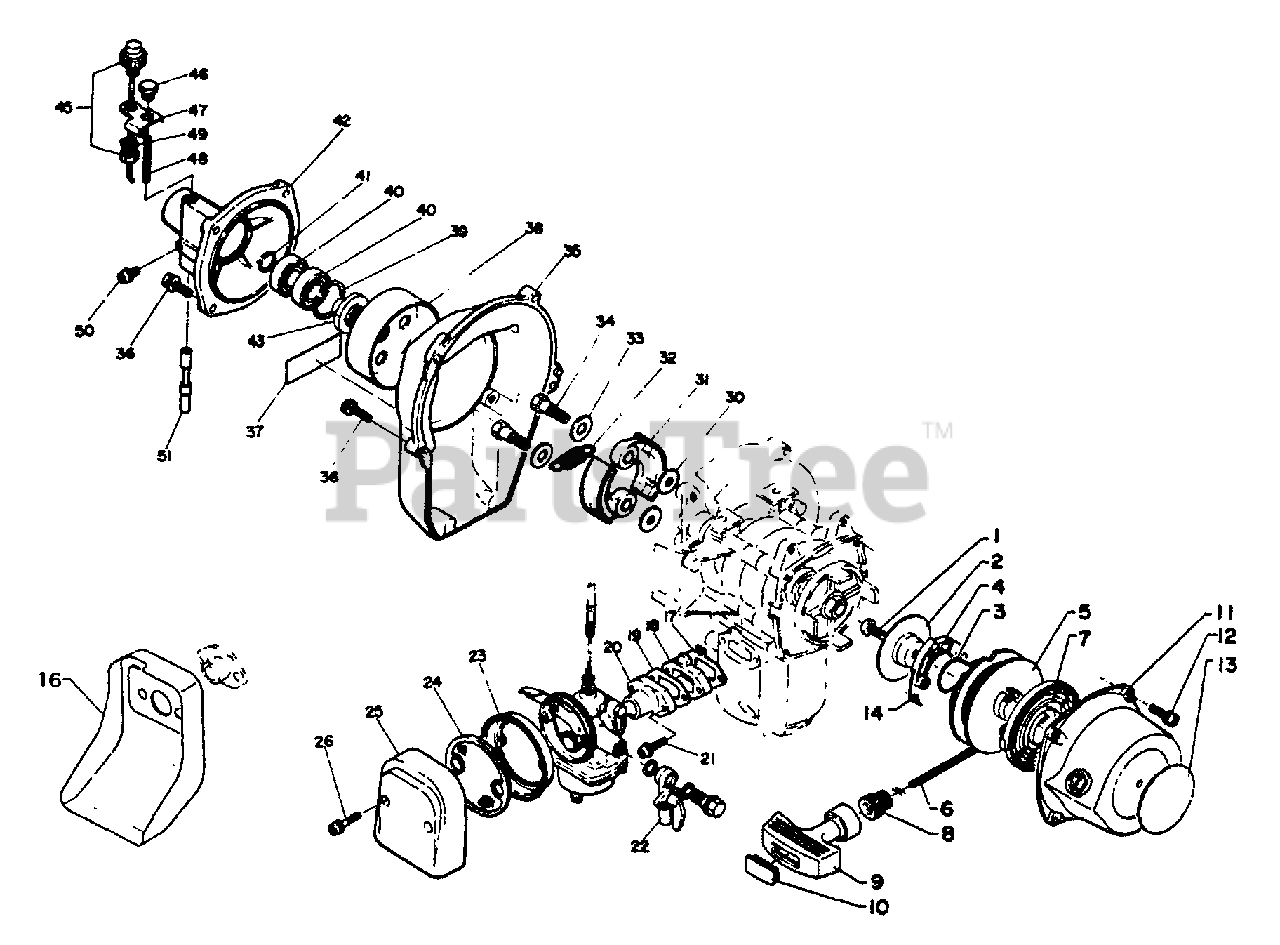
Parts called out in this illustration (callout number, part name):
1	SCREW
2	PLATE, FRICTION
3	SPRING
4	PAWL, STARTER
5	REEL, ROPE
6	ROPE, STARTER
7	SPRING, REWIND
8	GUIDE, ROPE
9	GRIP, STARTER
10	COVER, HANDLE
11	CASE, STARTER
12	SCREW 4×14
13	LABEL - ECHO
14	SPRING
16	INSULATOR
17	GASKET, INTAKE
18	INSULATOR
19	GASKET, INTAKE
20	ADAPTOR, CARBURETOR
21	SCREW 4×25
22	VALVE, FUEL
23	CASE, AIR FILTER
24	FILTER, AIR
25	COVER, AIR FILTER
26	SCREW 4×28
30	WASHER 6.2×19×1.0
31	SHOE, CLUTCH
32	SPRING, CLUTCH
34	BOLT, CLUTCH
35	CASE, FAN
36	SCREW 5×20
37	LABEL - MODEL
38	DRUM, CLUTCH
39	RING, SNAP 28
40	BEARING, BALL 6001 DDU
41	RING, RETAINING - 12
42	CASE, CLUTCH
43	SEAL, OIL
45	BUTTON, STOP
46	BOLT
47	BRACKET, SWITCH
49	WASHER, SPRING 8
50	SCREW 4×8
51	PIN, LOCK
